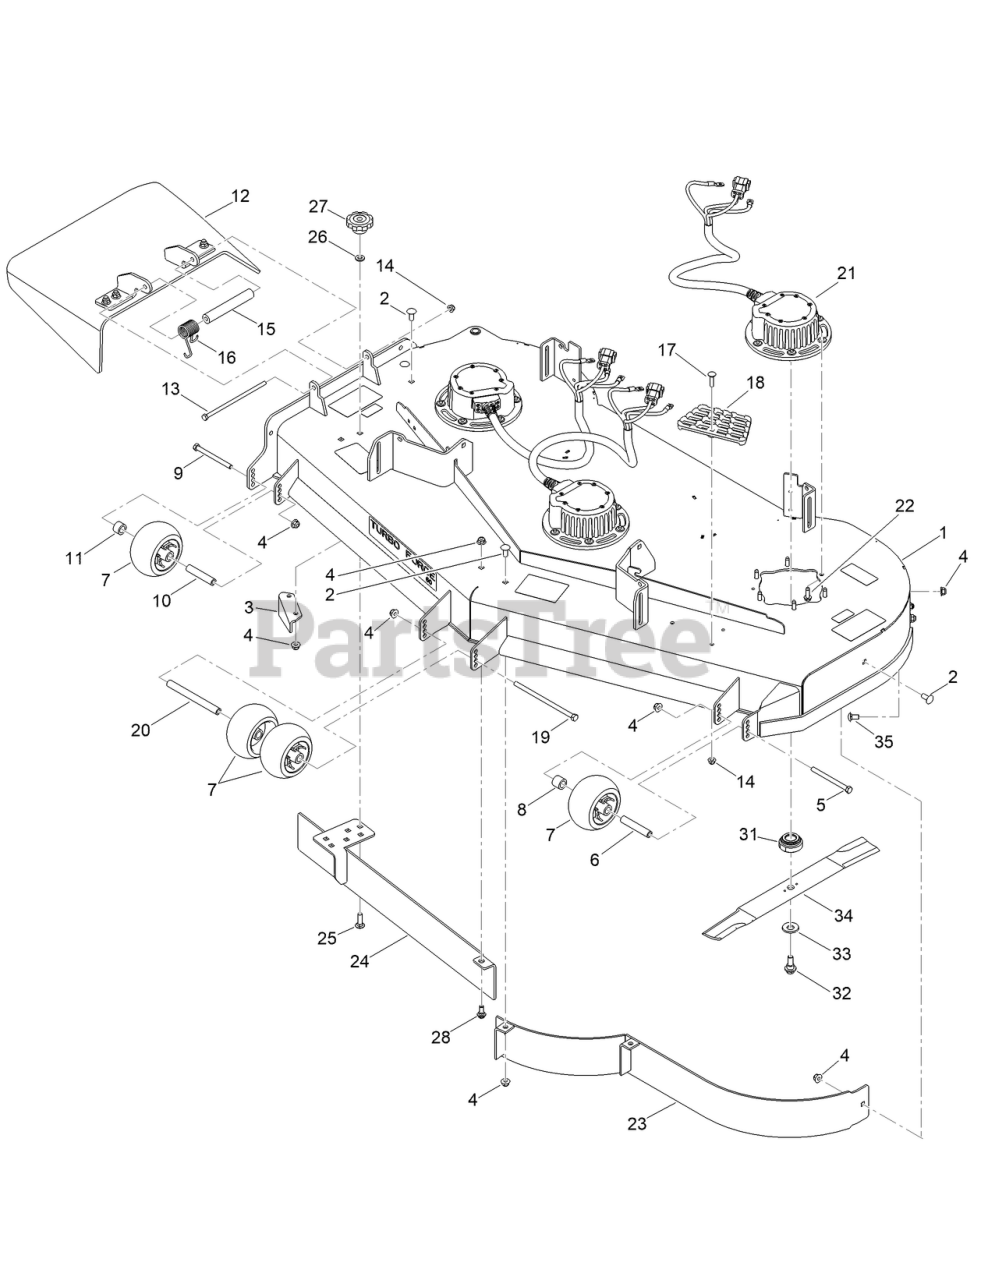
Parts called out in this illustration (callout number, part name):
1	DECK ASM-60IN
2	SCREW-CARR
3	BAFFLE-DISCHARGE
4	NUT-HF, NI
5	SCREW-HH
6	TUBE-SPANNER
7	ROLLER-SCALP, ANTI
8	TUBE-SPACER
9	SCREW-HH
10	TUBE-SHAFTING
11	TUBE-SPACER
12	RUBBER DEFLECTOR ASM
13	SCREW-HH
14	NUT-HF, NI
15	SPACER
16	SPRING-TORSION
17	SCREW-CARR
18	STEP-DECK
19	SCREW-HH
20	SPACER-WHEEL
21	MOTOR/GEN-48V,
22	SCREW-THD ROLL, HWH
24	BAFFLE-TURBO FORCE
25	BOLT-CARR
26	WASHER-HARDENED
28	BOLT-SHOULDER
31	RETAINER-BLADE
32	SCREW-SHOULDER,HWH
33	WASHER-BELLEVILLE
34	BLADE-20.5IN, MED SAIL
35	SCREW-CARR
